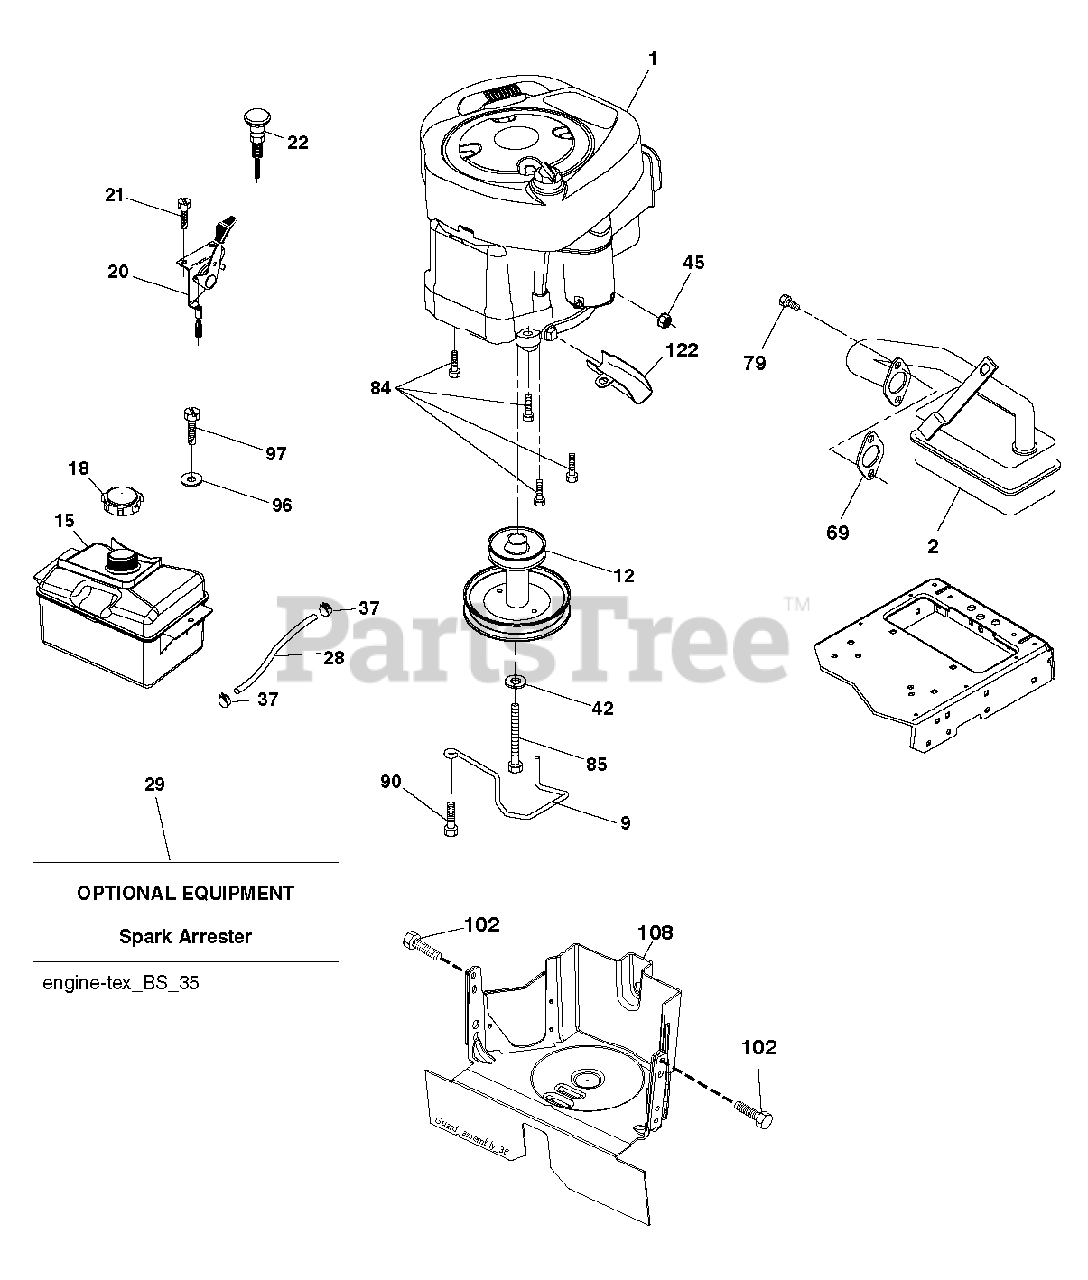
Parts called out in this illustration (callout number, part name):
9	Belt Keeper, 4 25"2 Blt 431
12	PULLY ENGINE
18	CAP ASM.FUEL.2.25"FR.
20	CONTROL.TH/CK.C.
21	SCREW.#10 X 0.750.BOS THREAD
28	LINE.FUEL.20
29	ARRESTER SPARK (OPTIONAL)
37	HOSE CLAMP
42	LOCKWASHER
45	NUT
69	REPL BY 532 27 22-93
79	SCREW.SOCKET HD.5/16-1
84	SCREW.3/8-16
85	BOLT HEX 7/16-20X4-1/4"
90	SCREW 3/8-16X1
97	SCREW HEXWSHR 1/4-20X3/4
102	SCREW 5/16-18X1
122	EXTENSION DRAIN OIL
